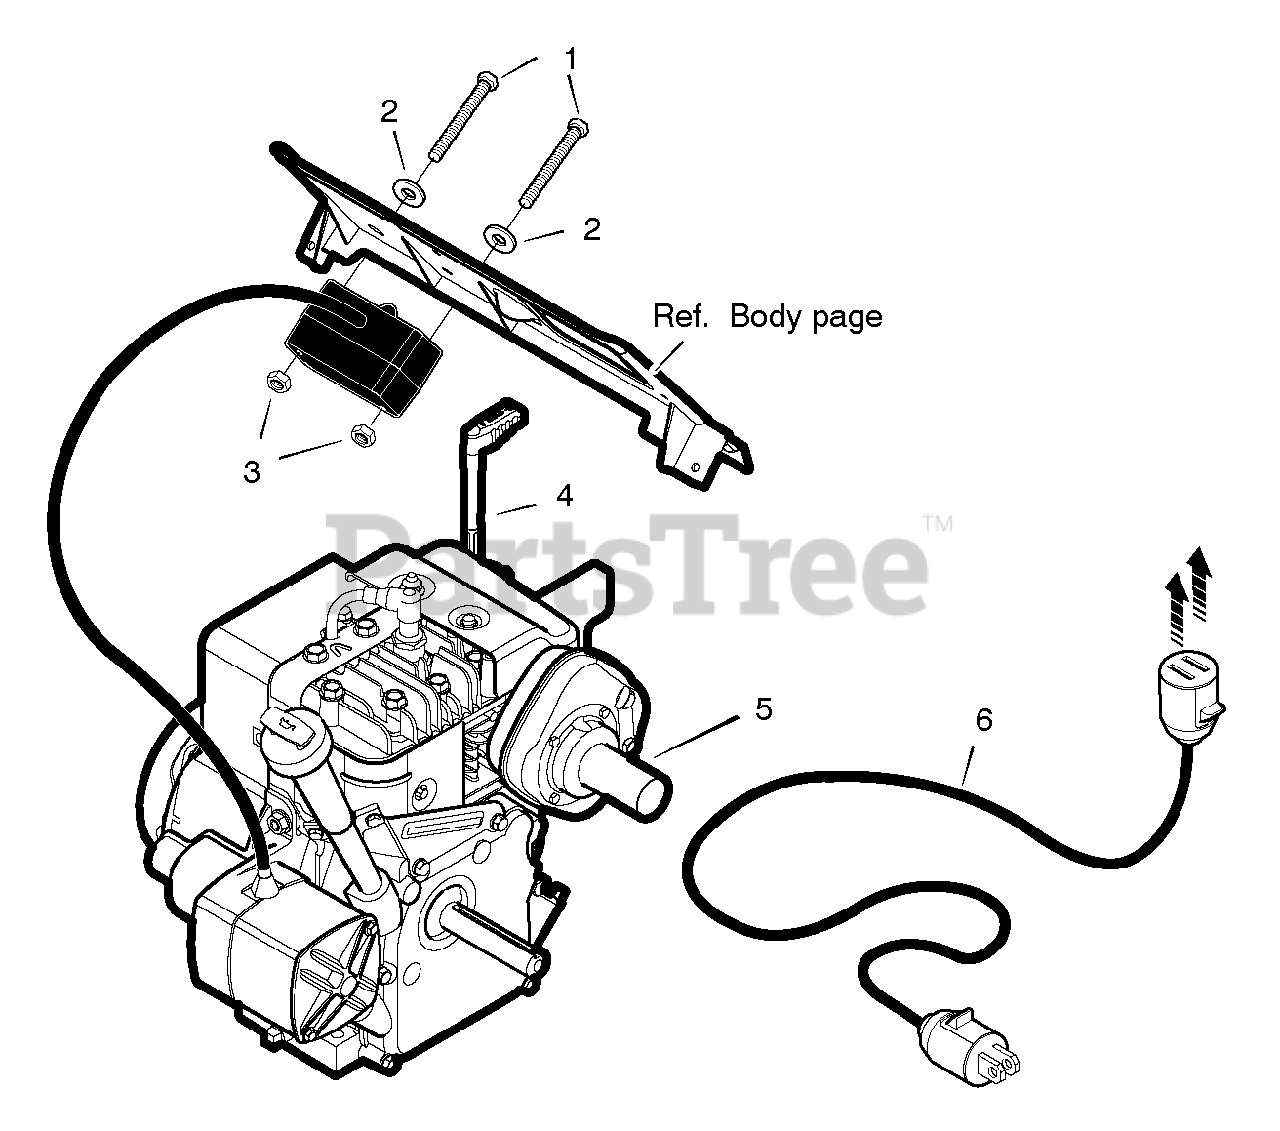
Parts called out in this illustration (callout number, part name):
1	Screw, No. 8-32 x 3.00
2	Washer
3	Nut, Keps No. 8
4	Lever, Choke *
5-1	Muffler *
5-2	Gasket, Muffler *
5-3	Bolt, Muffler
5-4	Washer, Split Lock
5-5	Nut, Hex 5/16-18
5-6	Bolt, Hex 5/16-18
6	CORD, Electric, 10FT. 110V
